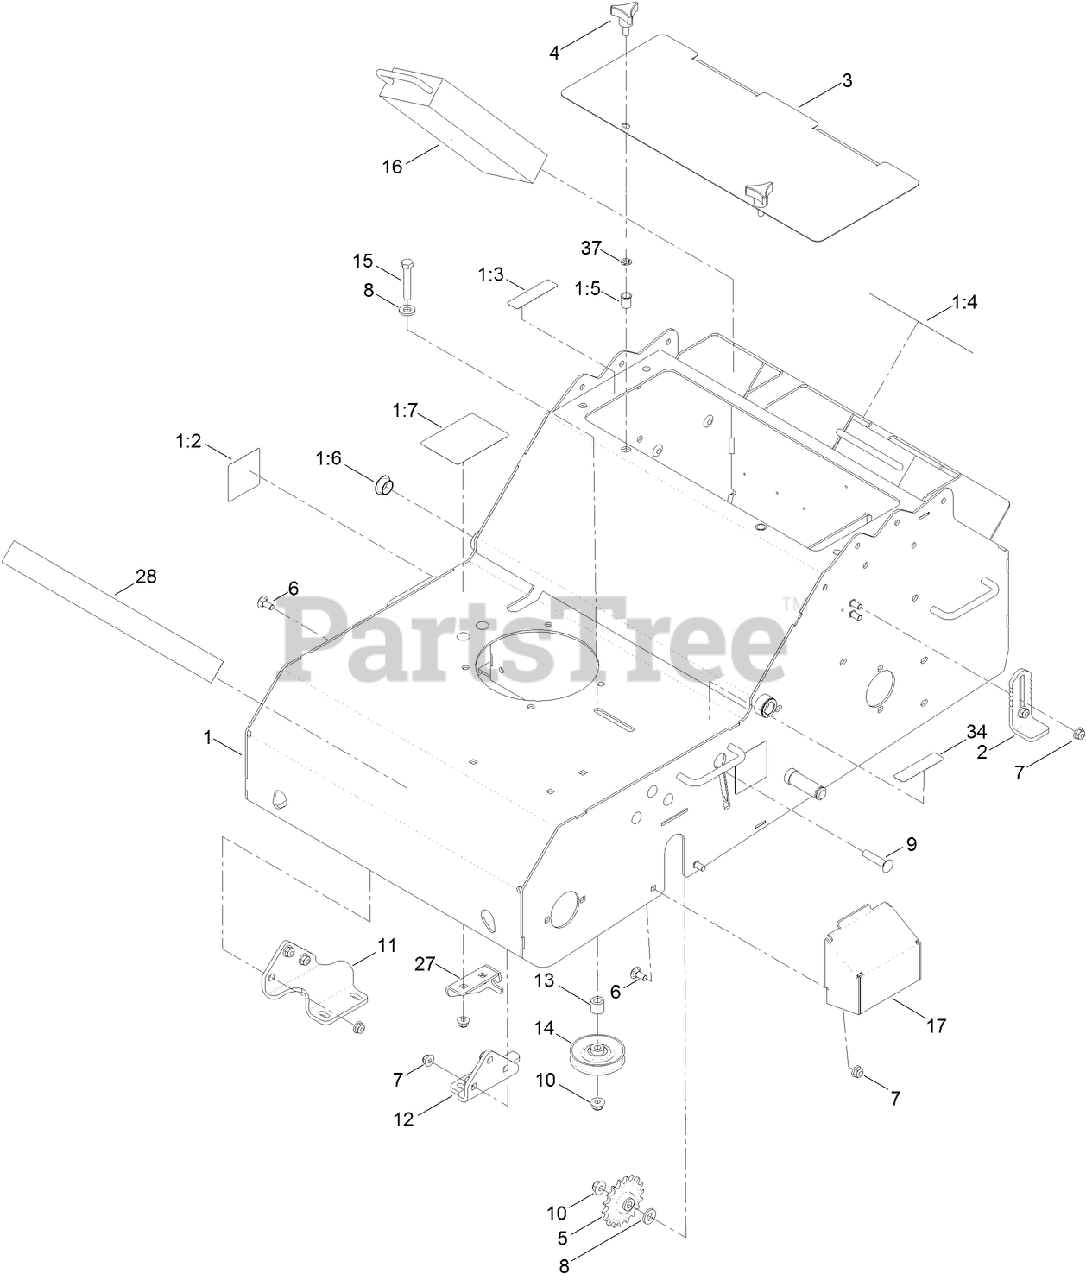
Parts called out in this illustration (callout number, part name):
1	FRAME ASM
1:2	DECAL-WARNING
1:3	DECAL-DANGER
1:4	DECAL-WARNING
1:5	NUT-INSERT
1:6	BUSHING-BRONZE
1:7	DECAL-SERVICE AID
2	STOP-DEPTH
3	COVER-ACCESS
5	SPROCKET-IDLER
6	BOLT-CARR
7	NUT-HF, NI
8	WASHER
9	SCREW-CARR
10	NUT-HF, NI
11	BRACKET-MOUNT AXLE, RH
12	BRACKET-MOUNT AXLE, LH
13	BUSHING-IDLER
14	PULLEY
15	SCREW-HH
16	WEIGHT-AERATOR
17	COVER-TRANSAXLE
27	BRACKET-MOUNTING, CABLE
34	DECAL-ARRESTER, SPARK
37	NUT-PUSH
